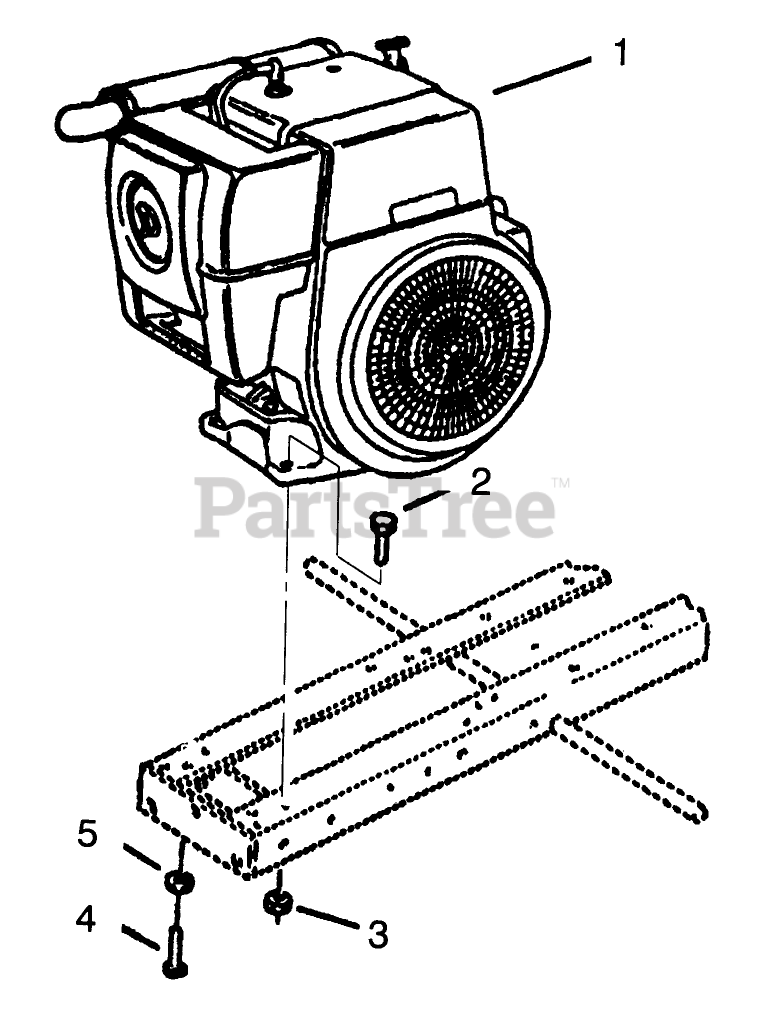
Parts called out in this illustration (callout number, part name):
2	SCREW-HH
3	NUT-LOCK, NI
4	SCREW-HH
5	WASHER-LOCK
